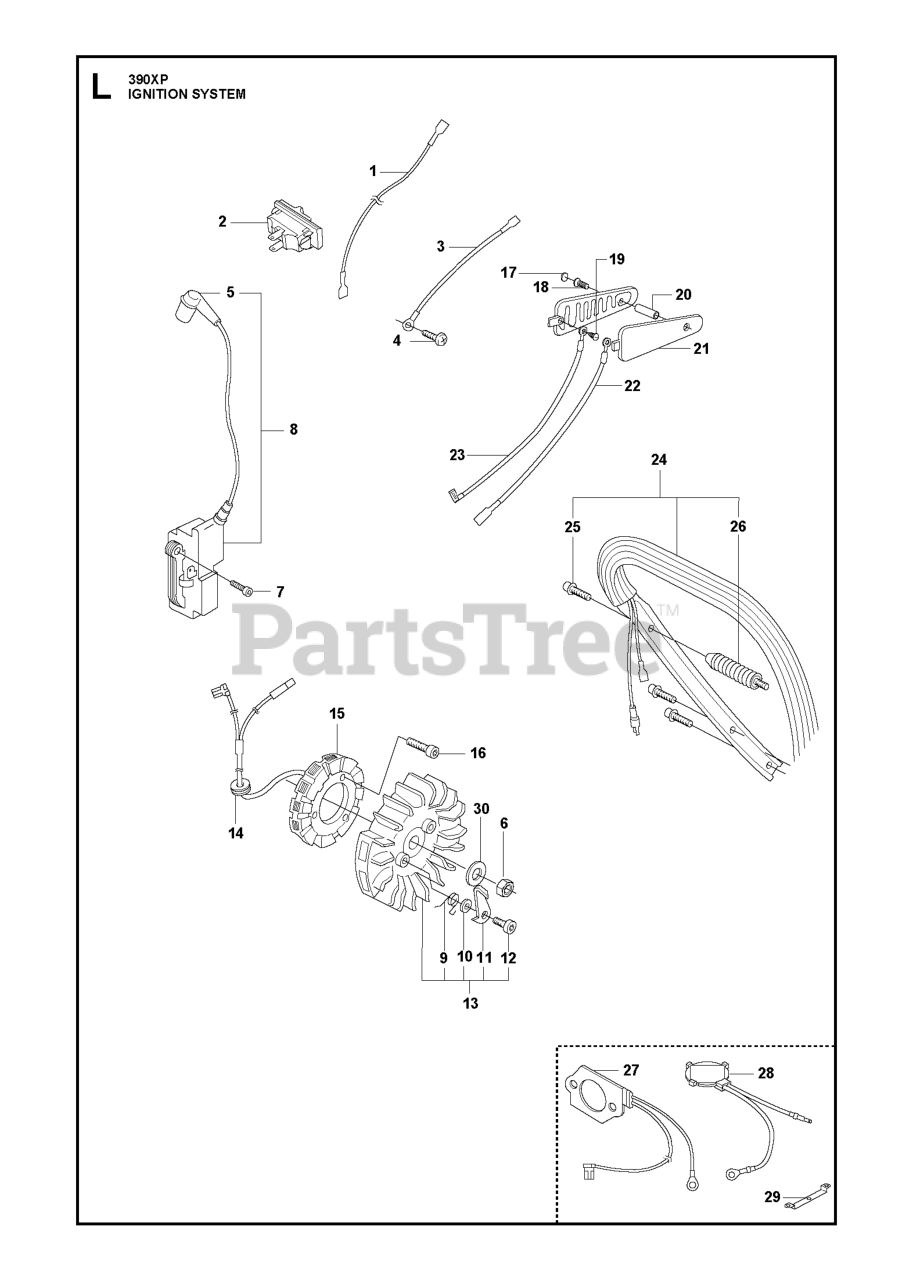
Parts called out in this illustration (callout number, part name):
2	START/STOP SWITCH
2	SWITCH (G)
4	SCREW CITXPANT
5	SPARK PLUG CONN. KIT
7	SCREW ITXSCM M5X20 T27 12.9 T
8	IGNITION MODULE
12	SCREW
13	FLYWHEEL
14	GROMMET
15	GENERATOR
17	WASHER
18	SCREW 3X10
19	Screws
20	SPACER
21	HANDLE
22	CABLE
23	CABLE
24	FRONT HANDLE HEATED
25	SCREW ITXSCFT
26	VIBRATION ABSORBER
27	FOIL ELEMENT
28	THERMOSTAT
